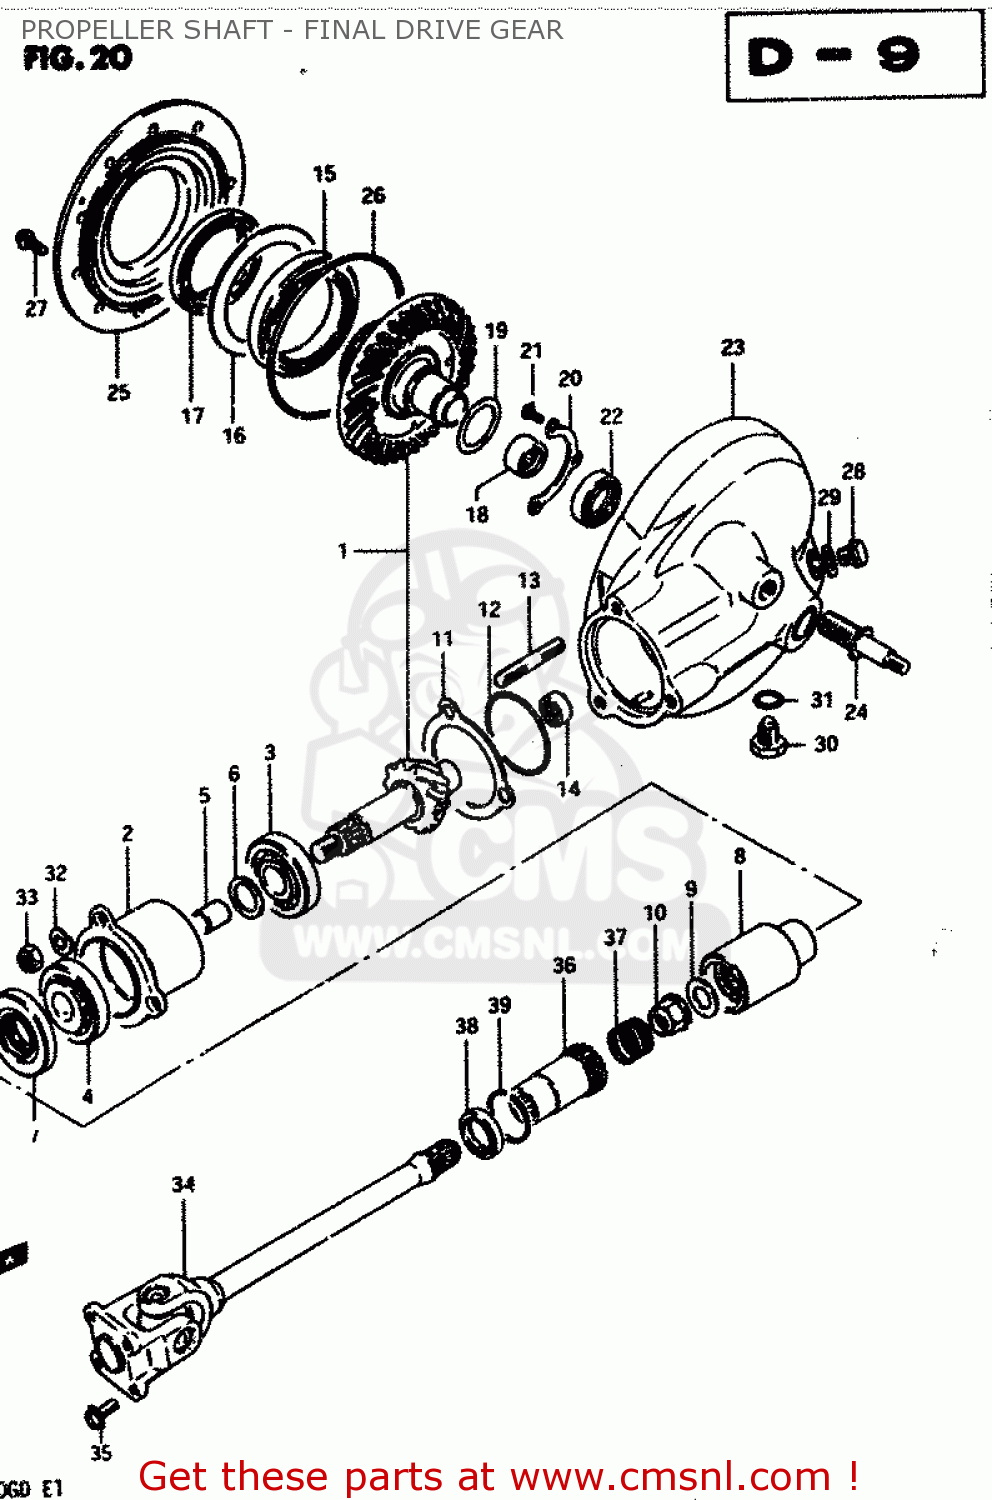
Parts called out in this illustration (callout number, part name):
1	GEAR SET,FINAL BEVEL
2	HOUSING,DRIVE GEAR
3	BEARING(25X52X19.25)
4	BEARING
5	SPACER (25.2X30X3.5)
6	SHIM (25X30X2
7	SEAL,OIL(32X54X7)
8	GEAR,FINAL DRIVE
9	WASHER(14X29X4)
10	NUT
11	SHIM,DRIVE GEAR HOUSING
12	O RING(D:2.4,ID:62.6)
13	STUD 10X30
14	BEARING(24X33X17)
15	BEARING(70X110X13)
16	SHIM,DRIVEN GEAR BEARING
17	SEAL,OIL(70X96X16)
18	BEARING(35X48X23.7)
19	SHIM,FINAL DRIVEN GEAR
20	RETAINER,FINAL DRIVEN GEAR BRG
21	SCREW 6X12
22	SEAL,OIL(30X42X7)
23	CASE ASSEMBLY,FINAL GEAR
24	STUD
25	CASE,FINAL GEAR BEARING
26	O-RING (D:3.1 ID:144.4)
27	BOLT
28	PLUG (14X12)
29	GASKET(14X19.2X2) (NAS)
30	PLUG
31	GASKET(14X19.2X2) (NAS)
32	LOCK WASHER
33	NUT
34	SHAFT ASSEMBLY,PROPELLER
35	BOLT(8X17)
36	COUPLING,PROPELLER SHAFT
37	SPRING
38	SEAL,OIL(30X40.5X5.5)
39	CIRCLIP
